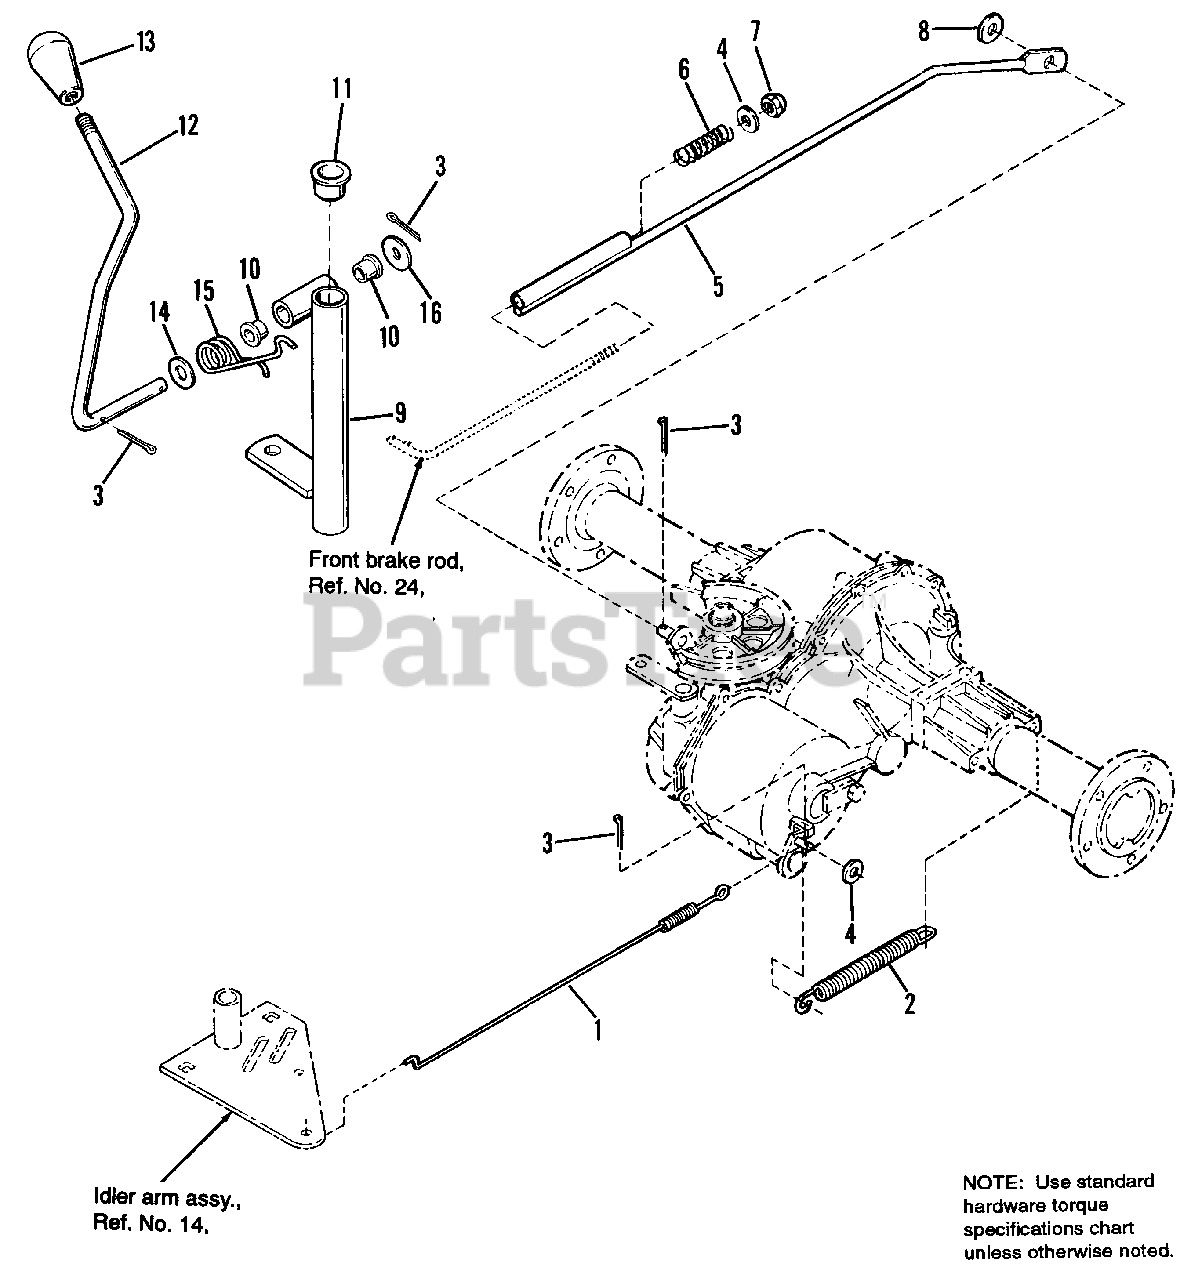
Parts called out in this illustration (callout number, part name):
2	SPRING, Extension
3	PIN, Cotter
4	WASHER, Plain
5	BRAKE ROD ASSY., Rear
6	SPRING, Compression, Brake
7	NUT, Hex, Nyloc, 5/16-18
8	WASHER, Plain, 5/16
9	SHIFT LEVER ASSY.
10	BUSHING, Plastic, 1/2
11	BUSHING, Plastic, 3/4
12	LEVER, Shift (Incl. Ref. 13) (Mfg. Nos. 1692024, 1692033, 1692301, 1692303)
12	LEVER, Shift (Mfg. Nos. 1692438, 1692444)
13	KNOB, Plastic (Mfg. Nos. 1692024, 1692033, 1692301, 1692303)
13	KNOB, Soft (Mfg. Nos. 1692438, 1692444)
14	WASHER, Plain
15	SPRING, Torsion
16	WASHER, Flat
